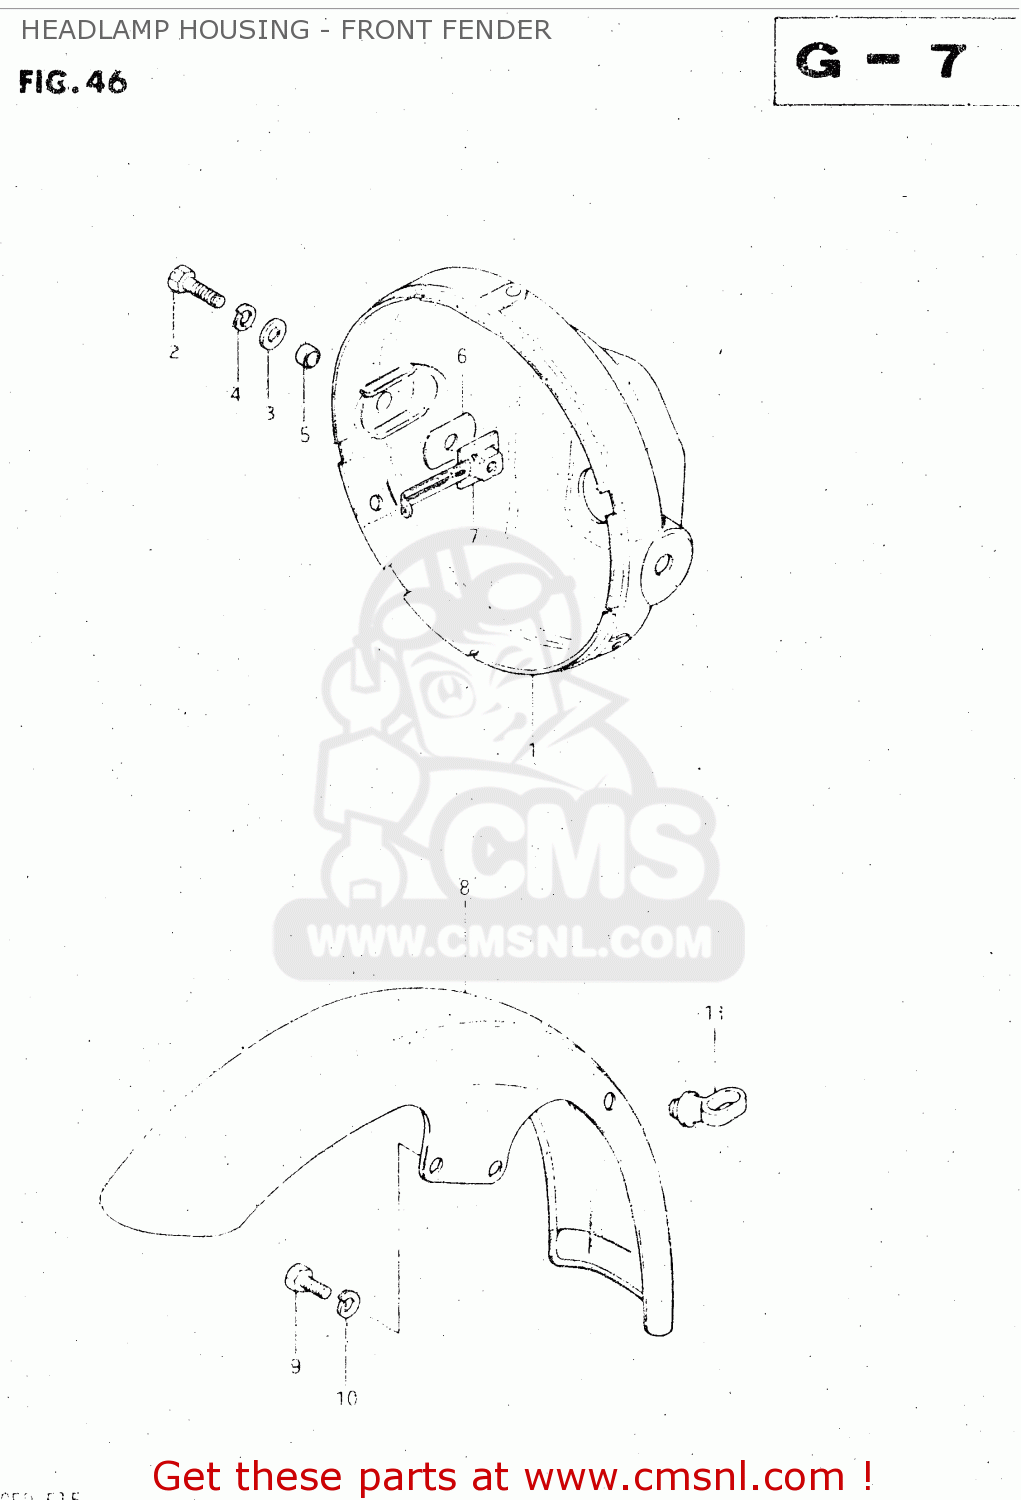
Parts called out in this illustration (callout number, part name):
1	HOUSING,HEADLAMP
2	BOLT
3	WASHER
4	LOCK WASHER
5	SPACER (8.8X12X7)
6	CUSHION
7	PLATE,HEADLAMP HOUSING
8	FENDER ASSY,FR
9	BOLT
10	LOCK WASHER
11	GUIDE,CABLE
